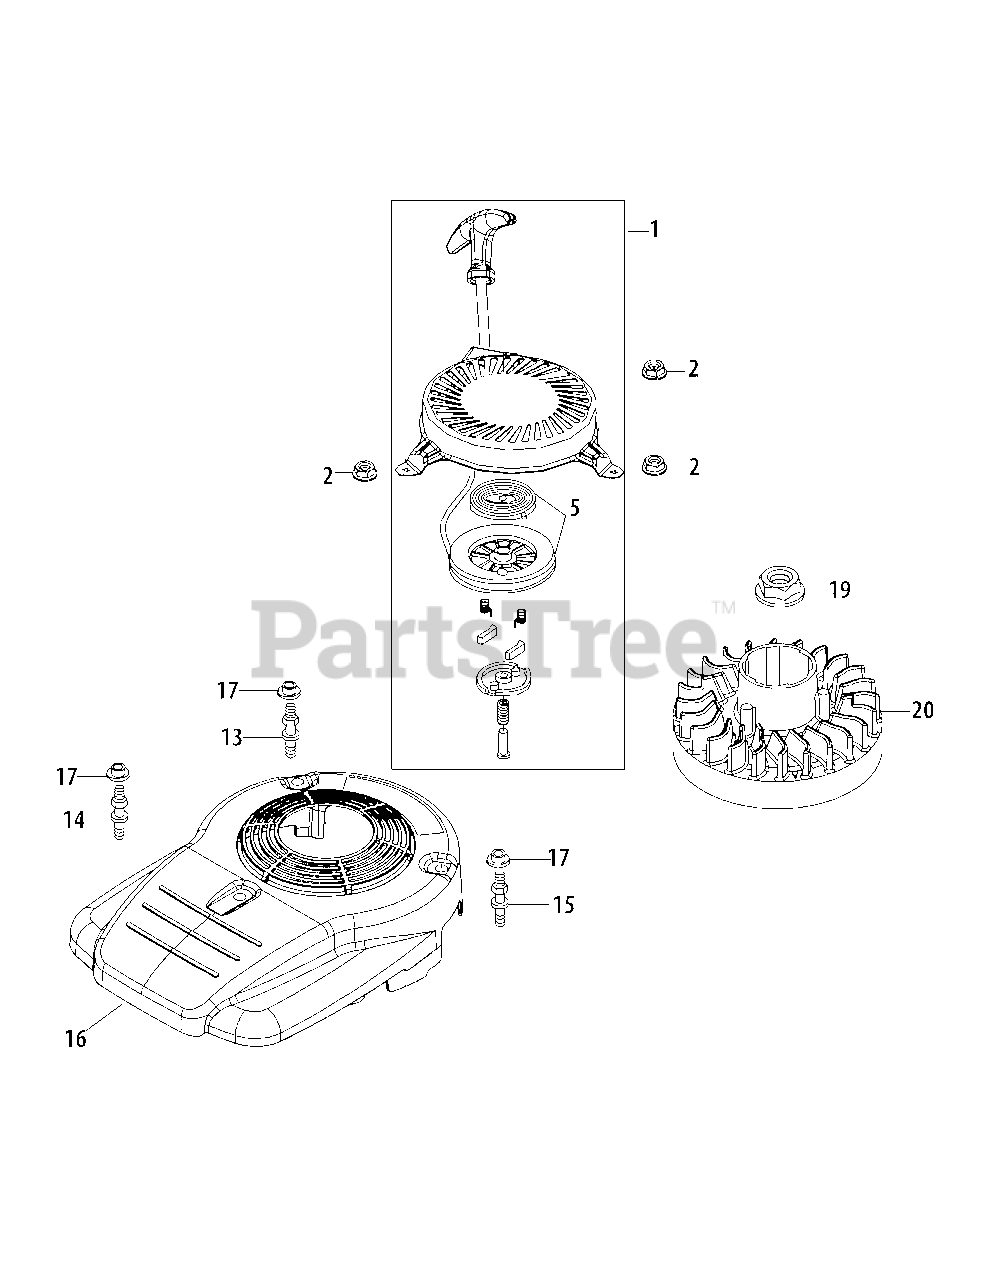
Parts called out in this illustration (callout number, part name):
1	Recoil Starter Assembly
2	Nut M6X10Mm
5	Recoil Spring
13	Stud Left/Black/Ye Zinc
14	Stud Front/Unmarked/Ye Zinc
15	Stud Right/White/Ye Zinc
16	Engine Shroud Only
16	Engine Shroud Assy (Incl. 17)
17	Engine Shroud Spacer
19	Flywheel Nut M14
